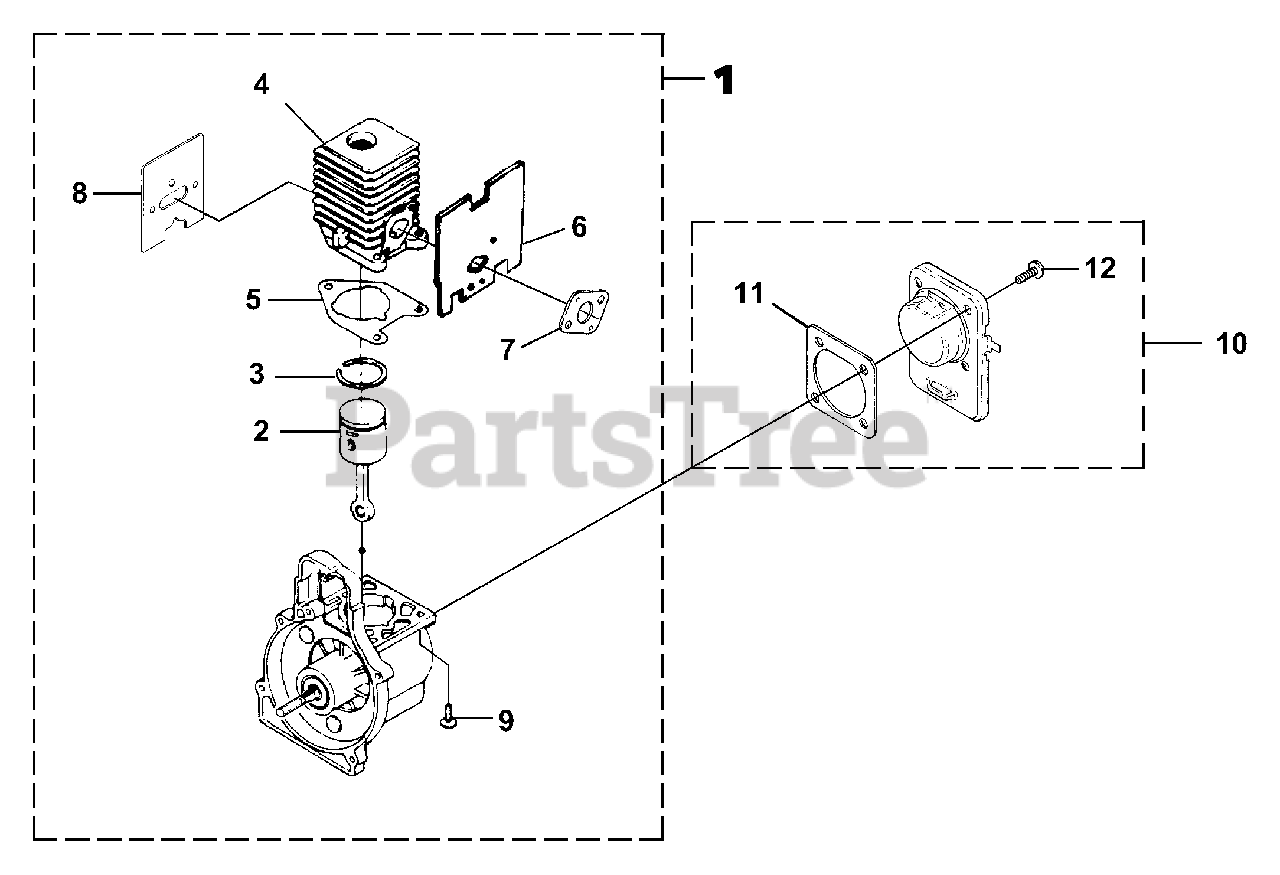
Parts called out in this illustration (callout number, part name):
1	SHORT BLOCK
2	PISTON & ROD ASSEMBLY
3	RING-Piston
4	CYLINDER ASSY.
5	GASKET-Cylinder
6	GASKET-Heat Dam
7	GASKET-Carburetor
8	GASKET-Muffler
9	SCREW-Sems (12-24 X 3/4")
10	CRANKCASE COVER ASSEMBLY
11	GASKET-Crankcase Cover)
12	SCREW-Sems (10-24 X 1/2")
